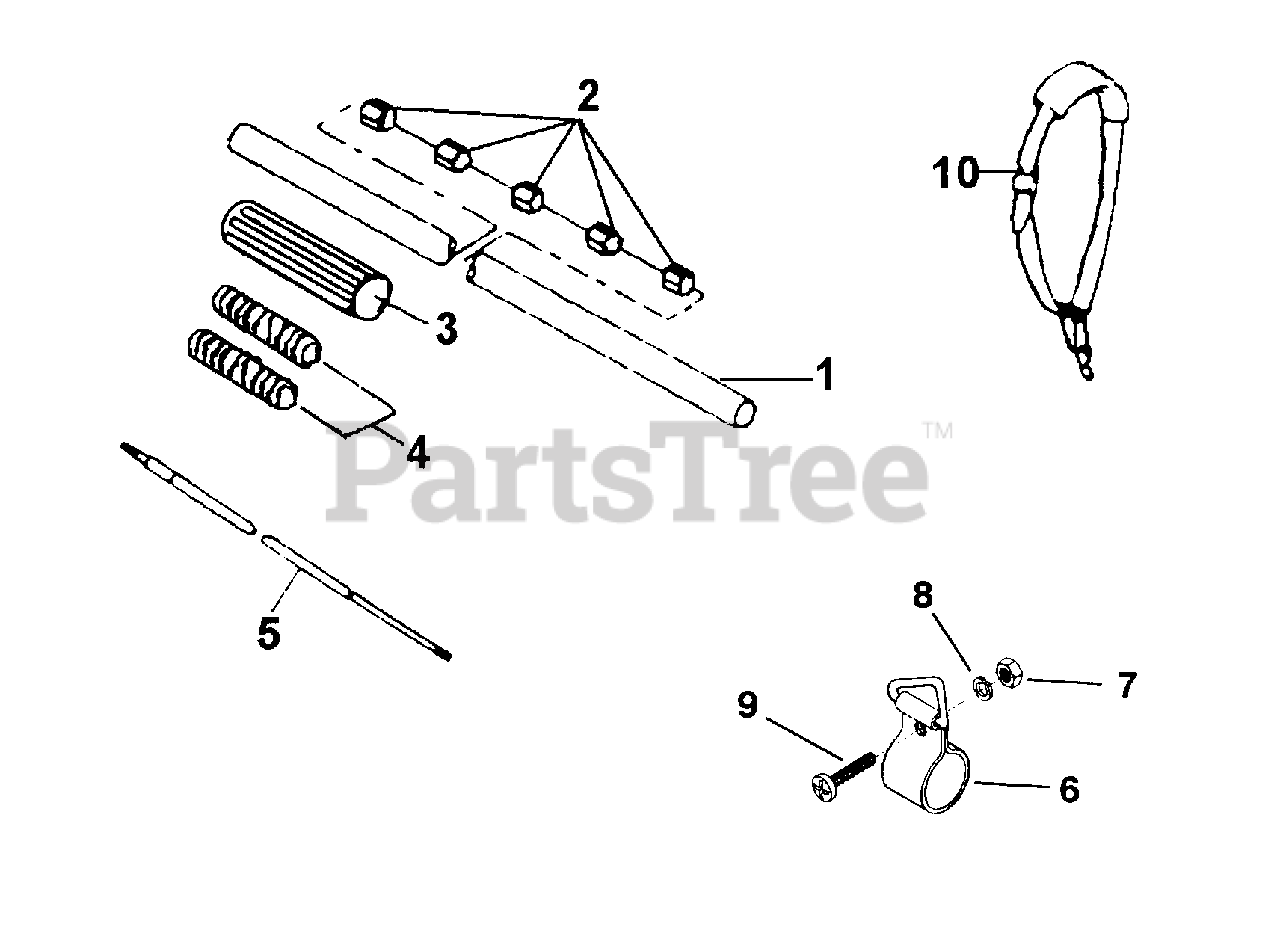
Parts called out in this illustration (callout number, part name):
1	DRIVESHAFT TUBE ASSY
3	GRIP - ANTI-VIBE
4	SPRING - ANTI-VIBE
5	DRIVESHAFT
6	HANGER ASSY
7	NUT
